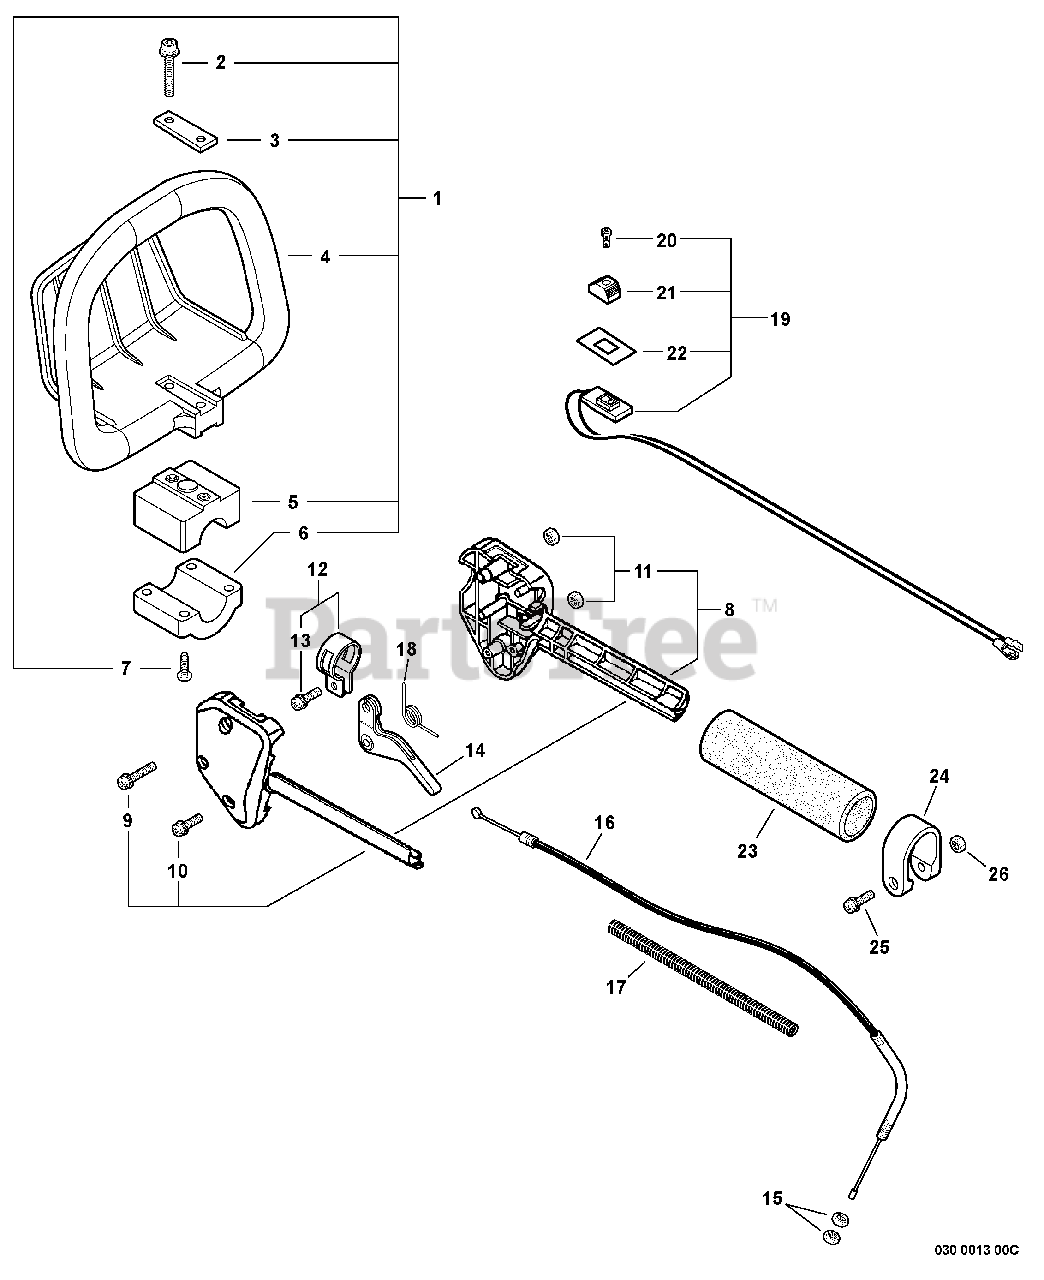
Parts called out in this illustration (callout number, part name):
1	FRONT HANDLE ASSY
2	BOLT 5×30
3	PLATE, EYE
4	HANDLE, SUPPORT
5	BRACKET, HANDLE - UPPER
6	BRACKET, HANDLE - LOWER
8	THROTTLE BRACKET SET
9	SCREW 5×35
10	SCREW 5×25
11	NUT M5
12	CLAMP KIT
13	SCREW 5×14
14	TRIGGER, THROTTLE
16	CABLE, THROTTLE
17	TUBE, PROTECTIVE - CORRUGATED
18	SPRING, TORSION
19	SWITCH ASSY, ON-OFF
20	SCREW 3×10
21	KNOB, SWITCH - ORANGE
22	LABEL, SWITCH
23	GRIP, HANDLE
25	SCREW 5×28
26	NUT M5
